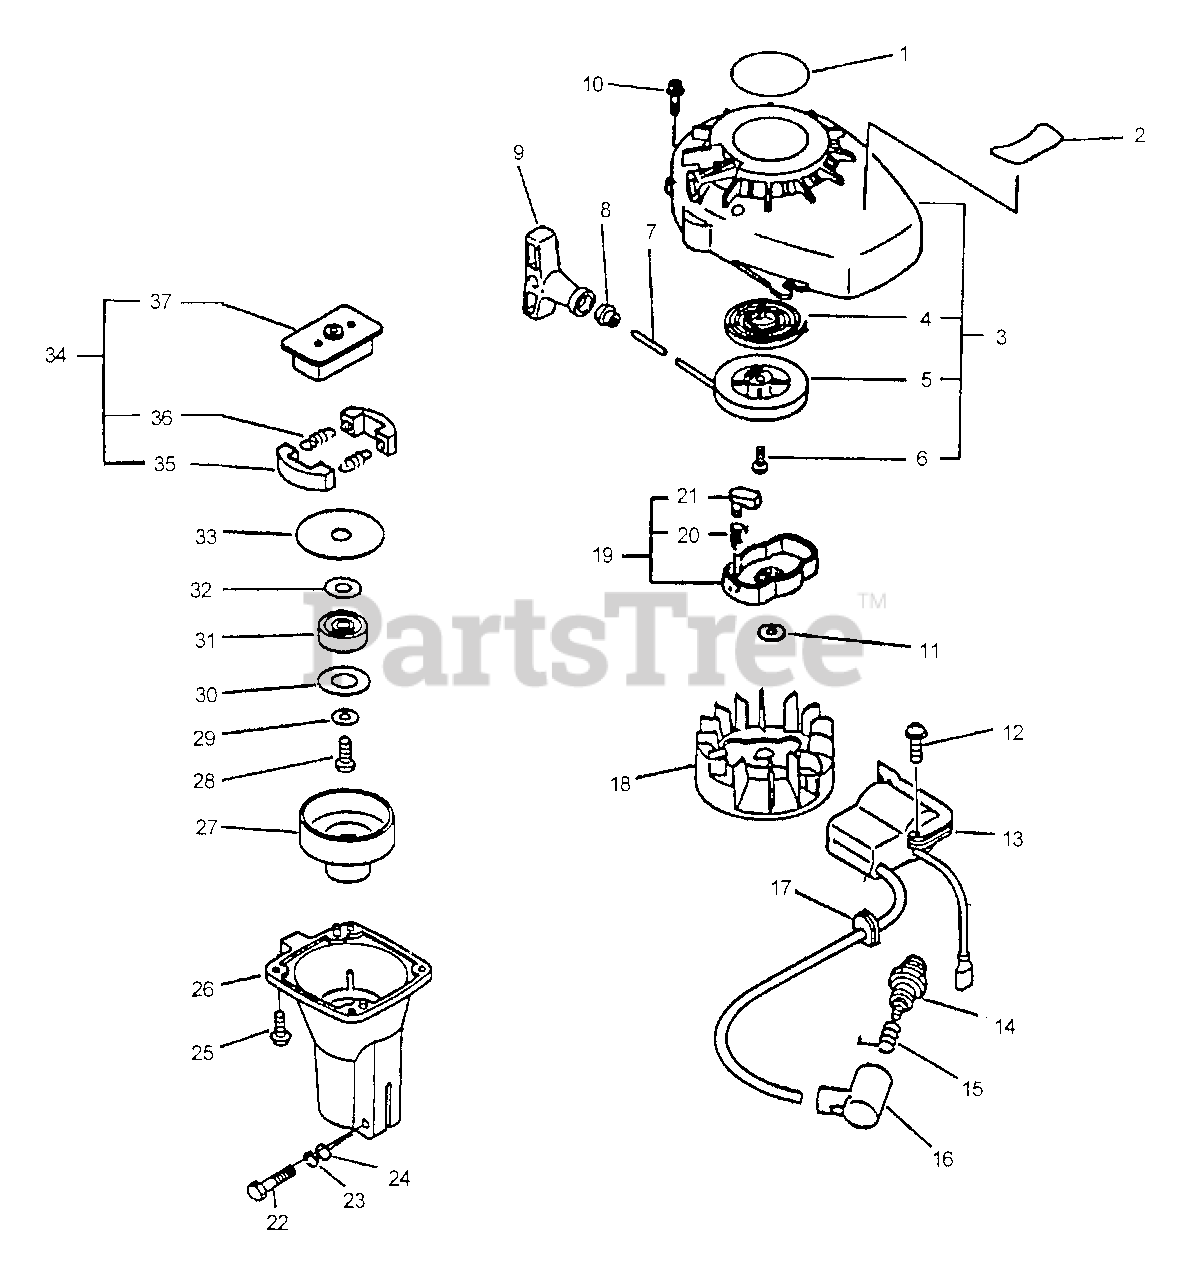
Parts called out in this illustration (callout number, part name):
1	LABEL, ECHO
2	LABEL, TC-2100
3	STARTER ASSY
4	SPRING, RECOIL
5	REEL, ROPE
6	SCREW
7	BULK STARTER ROPE - Ø 3.0 MM×61 M
8	GUIDE, ROPE
9	GRIP, STARTER
10	SCREW 4×16
11	WASHER, SPRING 8
12	SCREW 4×22
13	COIL, IGNITION
14	SPARK PLUG - BPM6A
14	SPARK PLUG - BPM-7Y
15	TERMINAL, SPARK PLUG
16	CAP, SPARK PLUG
18	FLYWHEEL
19	PAWL ASSY, STARTER
20	SPRING, RETURN
21	PAWL, STARTER - BLACK
22	BOLT - 5×25
22	BOLT 5
23	WASHER, SPRING 5
24	WASHER, FLAT 5.5×10×0.8
25	SCREW 4×14
26	CASE, CLUTCH
27	DRUM, CLUTCH
28	SCREW 6×12
29	WASHER, CLUTCH
31	BEARING, BALL 6000-2RLB
32	WASHER 10.5×18×1.6
33	PLATE, CLUTCH
34	CLUTCH ASSY
35	SHOE, CLUTCH
36	SPRING, CLUTCH
37	HUB, CLUTCH
